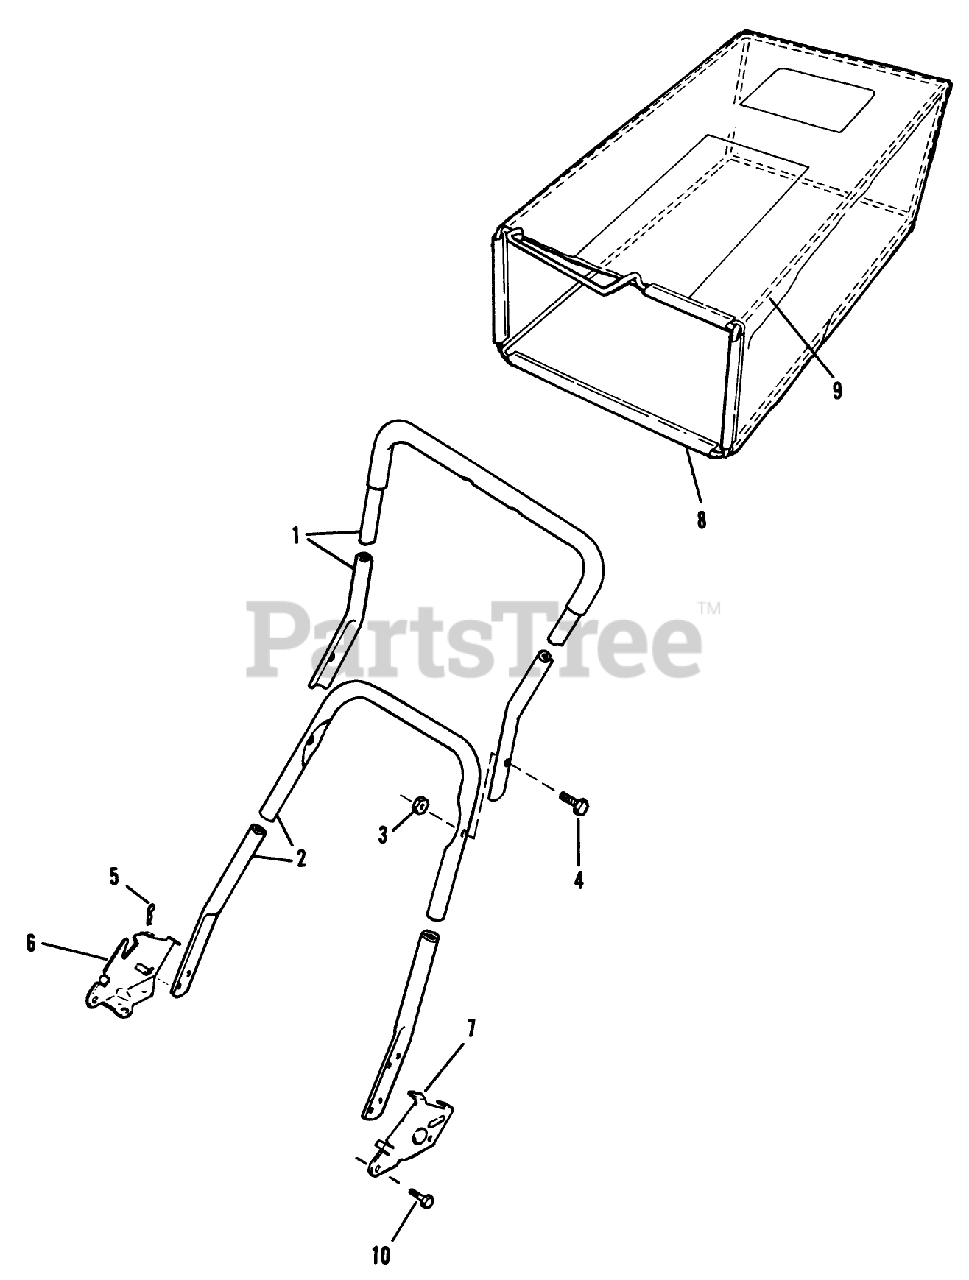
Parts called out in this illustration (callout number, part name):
2	HANDLE SECTION *B
3	LOCKNUT E
5	HAIR PIN
